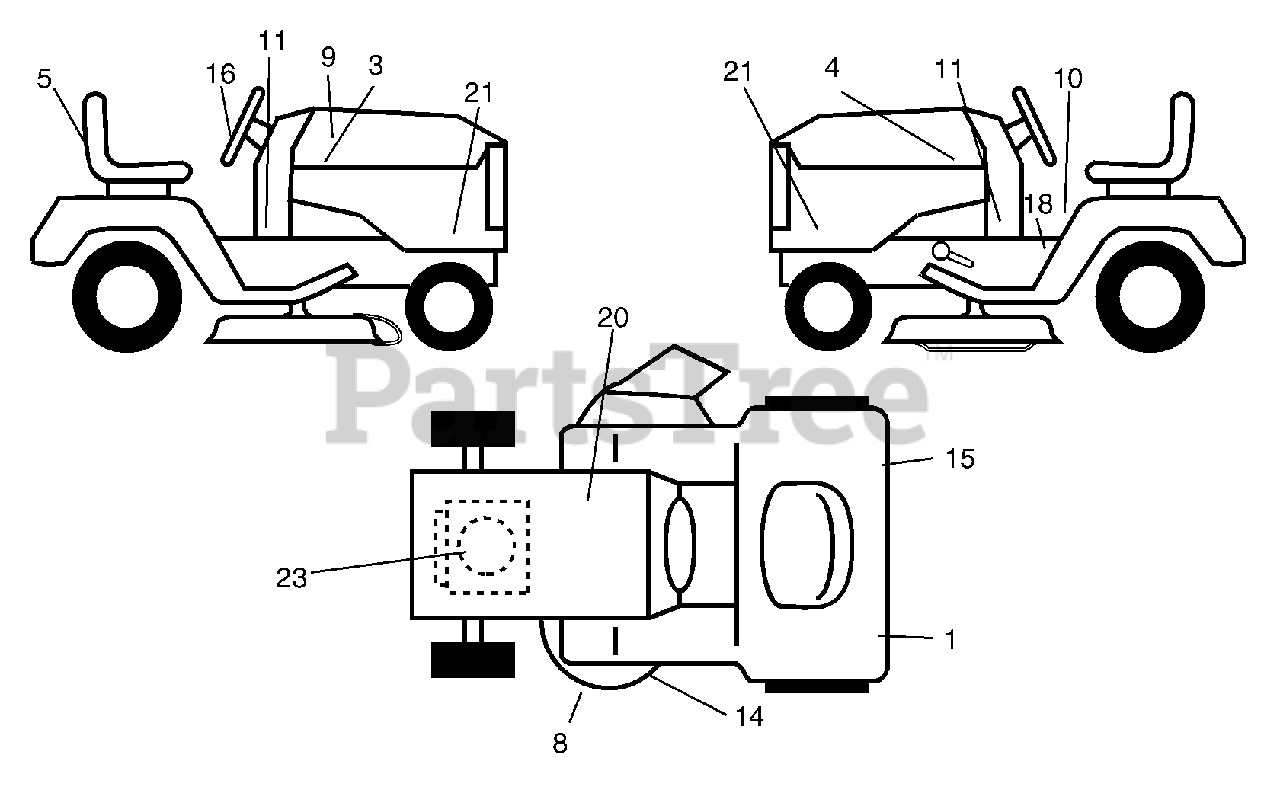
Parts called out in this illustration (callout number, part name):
1	Reflector, LH
3	Decal, Hood RH
4	Decal, Hood LH
5	Decal, Fender
8	Decal, Deck, Caution
9	Decal, Replacement Hood
10	Decal, Fender, Danger
11	Decal, Panel, Dash
14	Decal, V-Belt, Schematic
15	Decal, Reflector, RH
16	Decal, Steering Wheel
18	Decal, Fender Opr.
20	Decal, Battery
21	Decal, Hood, Side Panel
23	Decal, Engine
